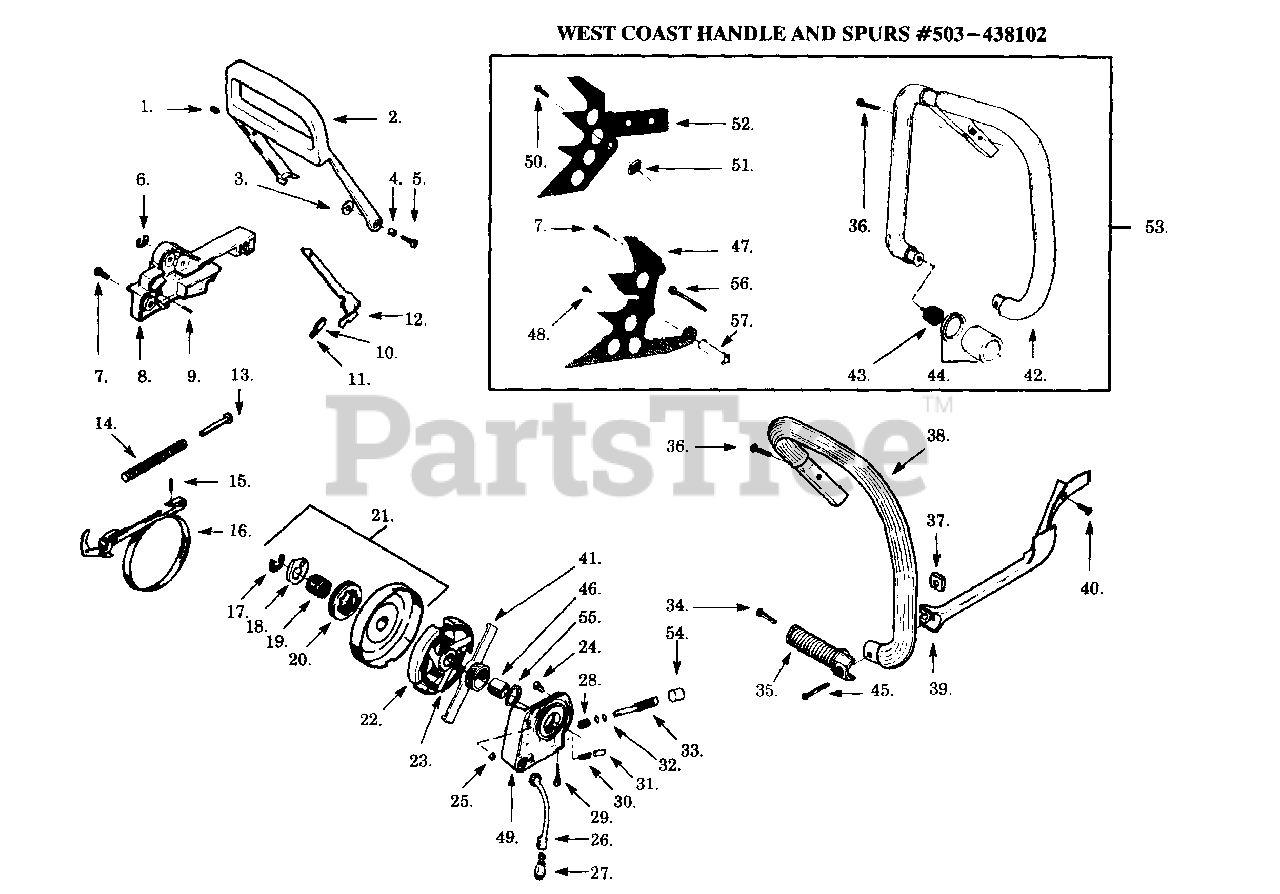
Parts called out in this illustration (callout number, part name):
2	Actuator
8	Brake Housing
12	Actuator Arm
18	Washer
19	Clutch Bearing
20	Rim-3/8"x7T
20	Rim-3/8"x8T
21	Clutch Drum Ass'y. (Incl. 17-20)
22	Clutch Ass'y.
23	Clutch Spring
25	Seal Ring
26	Oil Pickup Tube
27	Oil Pickup
29	Adjusting Screw
33	Pump Piston
37	Nut
38	Handlebar
40	Screw
41	Worm Gear
42	Handlebar
45	Screw
47	Inner Spur
48	Screw
49	Oil Pump Ass'y (Incl. 25, 28-33, & 54)
50	Screw
51	Nut
52	Outer Spur
53	Wrap Around Handlebar Kit (Incl. 7, 36, 42-44, 47, 48, 50-52, 56 & 57,)
54	Dust Shield
55	Washer
